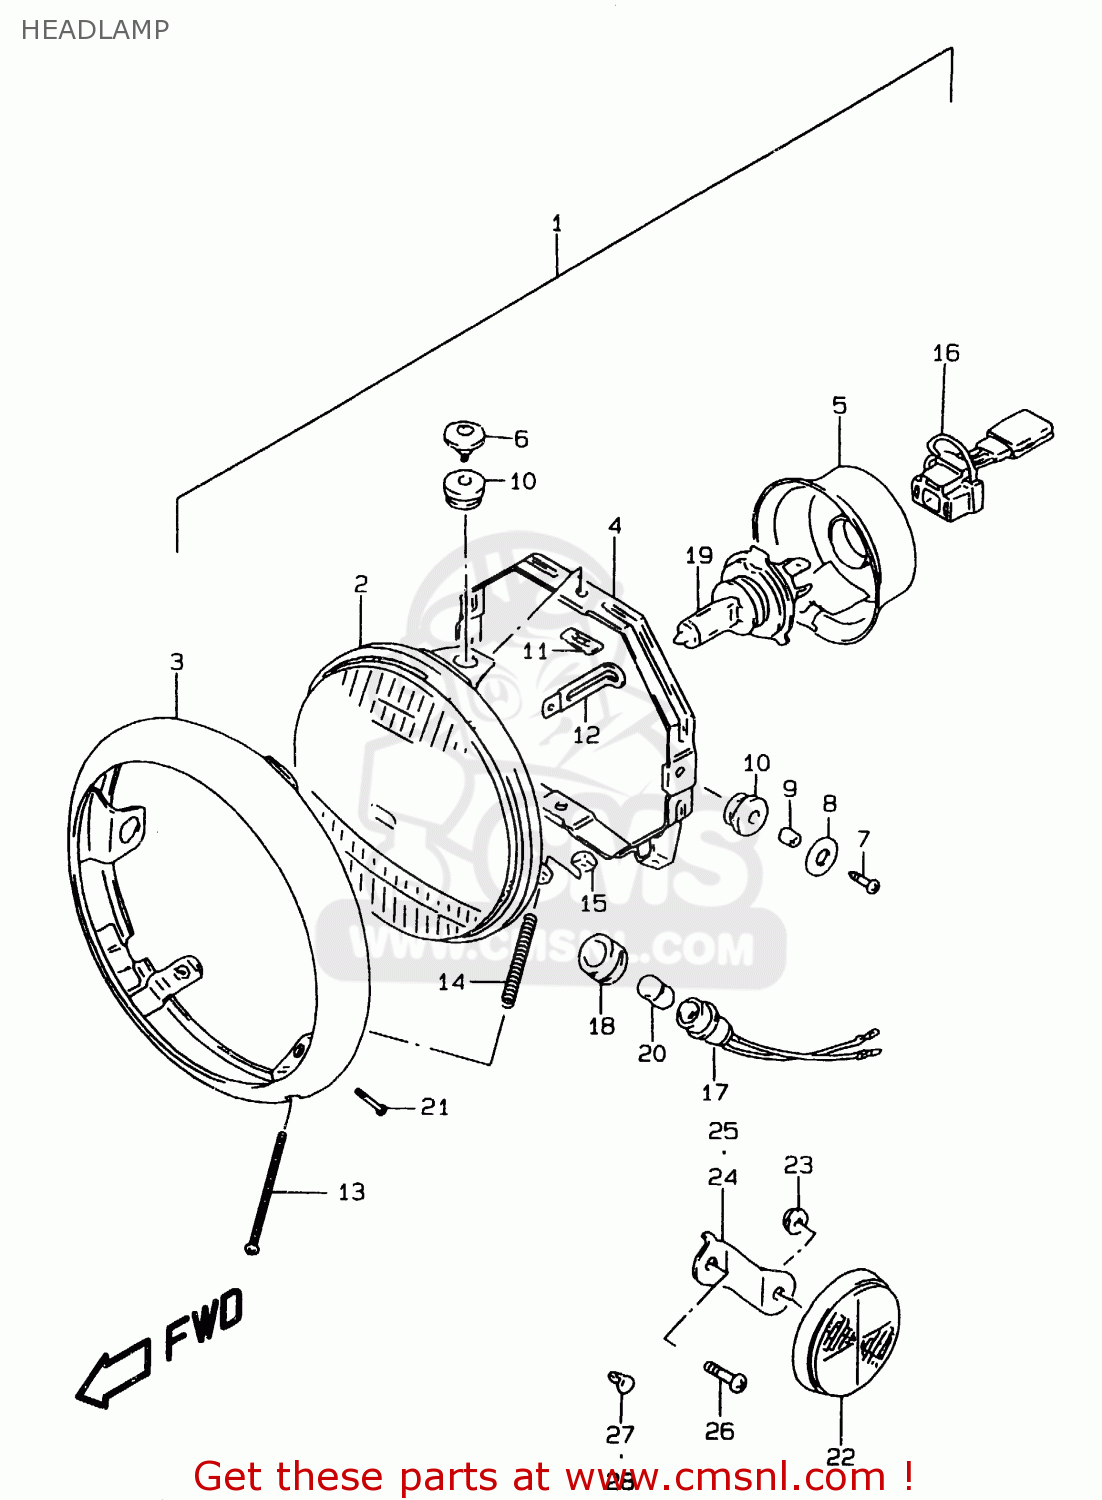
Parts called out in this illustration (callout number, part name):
1	HEADLAMP ASSY
2	UNIT
3	RIM
4	RING,MOUNTING
5	COVER,SOCKET
6	SCREW,MOUNTING
7	SCREW(5X14)
8	WASHER(5.5X18X1)
9	SPACER
10	CUSHION
11	NUT
12	CLAMP(L:65)
13	SCREW,ADJUSTING(4X50)
14	SPRING
15	NUT
16	SOCKET
17	SOCKET
18	JOINT,RUBBER
19	BULB(12V60/55W,H4)
20	BULB(12V4W)
21	SCREW
22	REFLECTOR,REFLEX FR
23	NUT
24	BRACKET,FRONT SIDE RH
25	BRACKET,FRONT SIDE RH
26	SCREW
27	CLIP(BLACK)
28	CLIP
